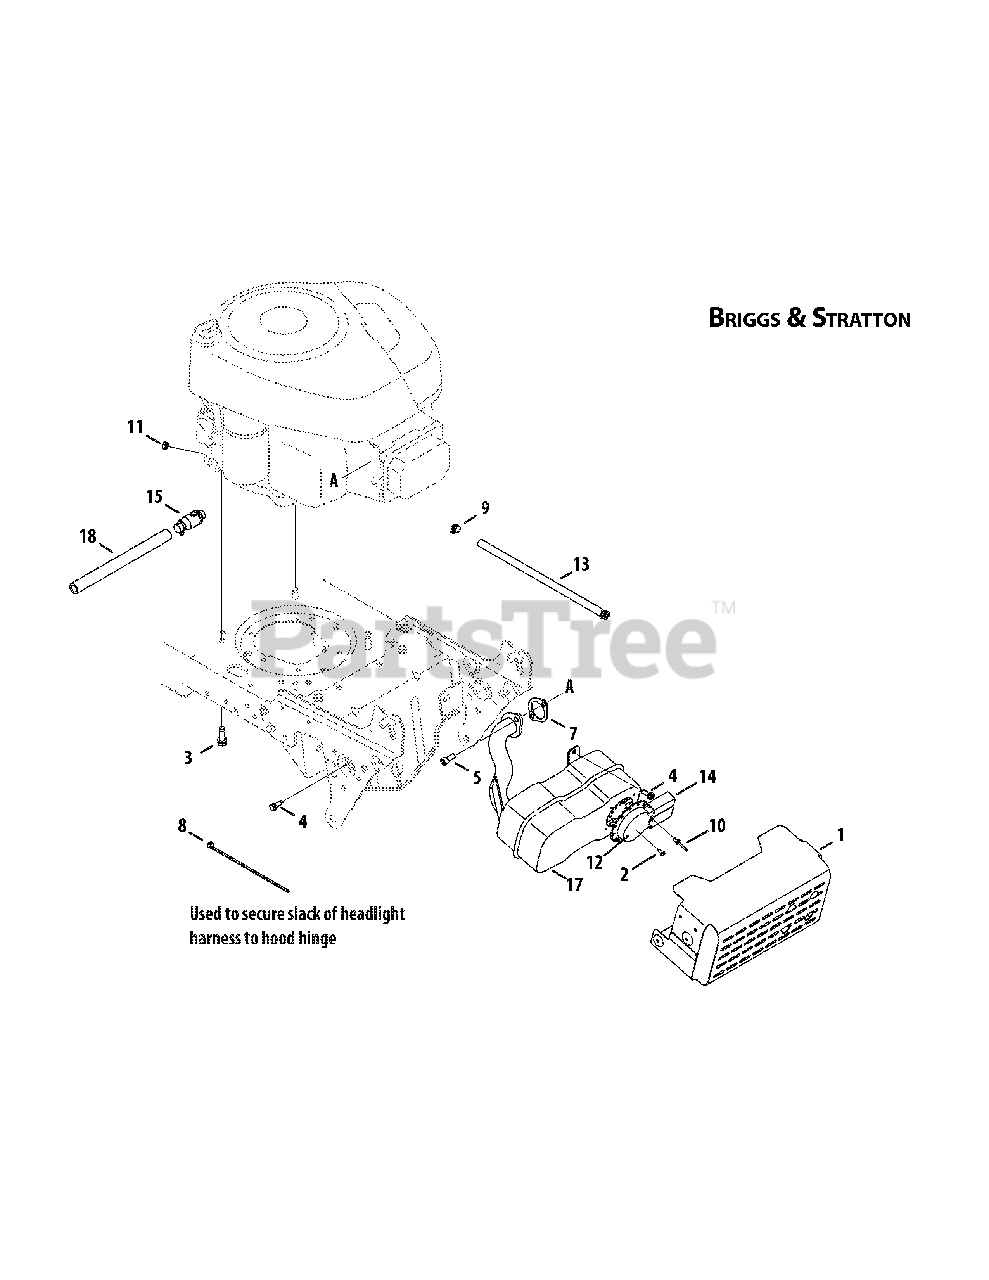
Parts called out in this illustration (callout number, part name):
1	Shield, Muffler
2	Screw, #8-18, 0.500
3	Screw, Hex, 3/8-16 x 1.00
4	Screw, Hex, 1/4-20, 0.500
5	Screw, Hex, 1/4-20, 0.750
7	Exhaust Gasket
8	Cable, Tie, 3/16 x .05 x 7.4
9	Hose Clamp
10	Rivet, Pop, .188 x .325
11	Sems Nut, 1/4-20
12	Deflector, Muffler
13	Fuel Line, Low Permeation
14	Extension, Deflector
15	Drain, Oil
17	Muffler, Single Inlet
18	Extension Hose, Oil Drain
